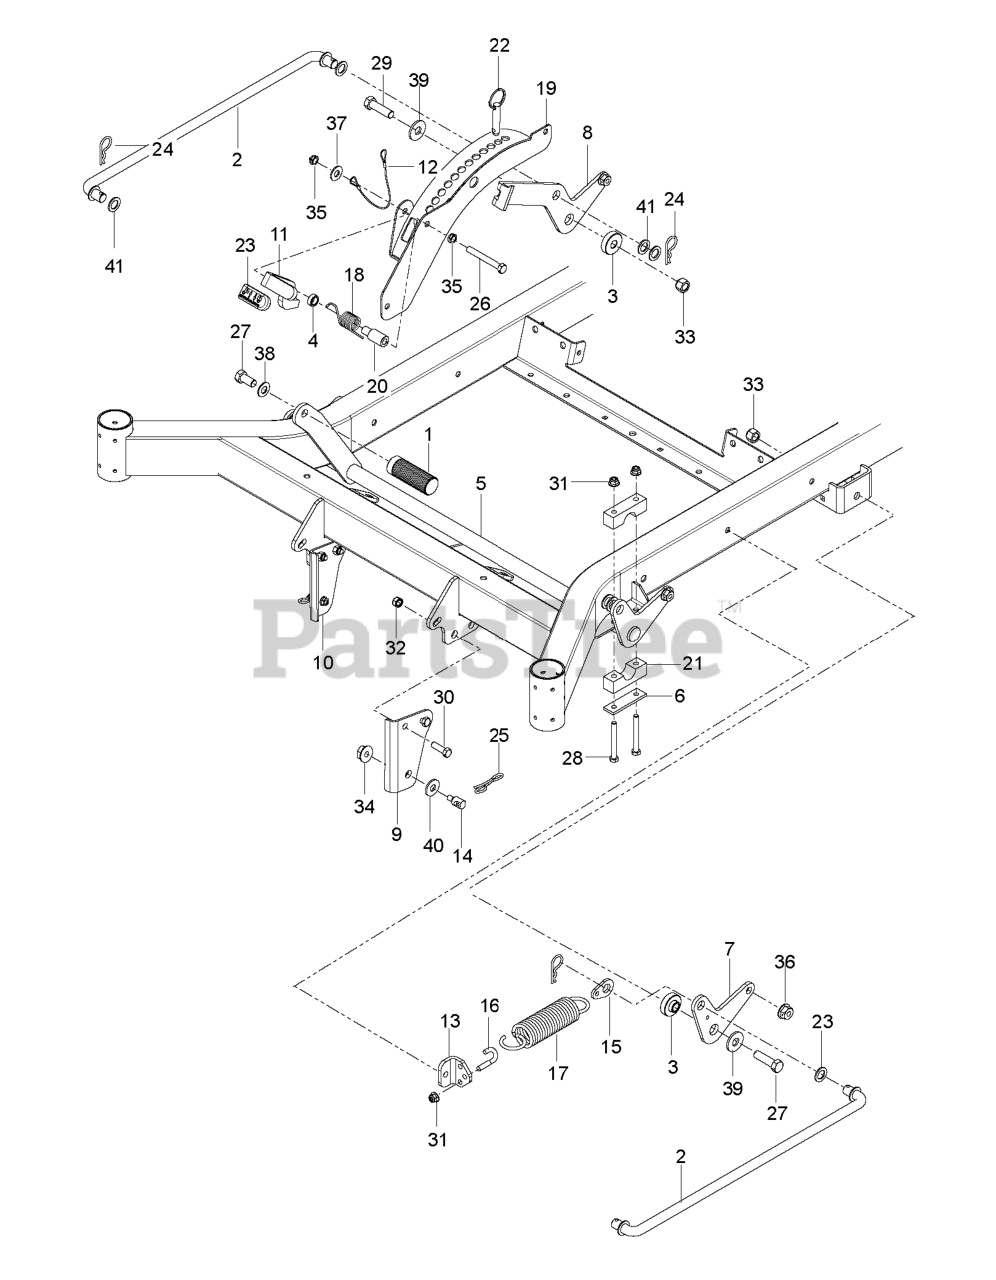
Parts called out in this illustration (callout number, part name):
1	PEDAL, DECK HEIGHT
2	CROSS LINK
3	SPACER.IDLER.METAL.POWDER
4	SPACER, .3
5	LIFT.PNT.MZ.DECK.WELD.E-DIP
6	REINFORCEMENT.PLATEX431
7	BELLCRANK, RR, LIFT
8	BELLCRANK, RR, RT
9	BRACKET.PNT.SUSP.CHAS.FR.LH.OR
10	BRACKET.PNT.SUSP.CHAS.FR.RH.OR
11	LATCH, TRANSPORT
13	MOUNT, SPRING
14	STUD.FASTNER.W/ANTI-ROTATE
15	TAB, SPRING
16	J-BOLT
18	SPRING, TORSION
19	HEIGHT, ADJUST, DECK
20	PIVOT, LATCH, TRANSPORT
21	PILLOW BLOCK
22	PIN, 1/2 X 1 1/2, DETENT RING
23	GRIP, TRANSPORT-RELEASE
24	PIN, COTTER 1 3/4
25	PIN.COTTER.7/16.BOW TI.
26	BOLT.HEX.FIN.3/8-16 X 3.GR5
27	HHCS 1/2-13 X 1
28	BOLT HEX
29	HCS 1/2-13 X 1 3/4 GR 8
30	HCS 3/8-16X1.GRD.5.ZD
31	5/16-18 NYLOC FLANGE NUT
32	NUT 3/8-16 NYLOC
33	NUT.LK.W/WSH.1/2.
34	NUT LOCK HEX FLANGE 5/16-18
35	NUT HEX 3/8-16 NYLON, THIN
36	NUT LOCK FLG 3/8-16 UNC
37	RP WASHER 3/8 FLAT
38	CONTACT BELLSPR 1/2
39	WASH USS FLAT 1/2
40	WASHER.CLEAR.ZINC
41	BUSHING
